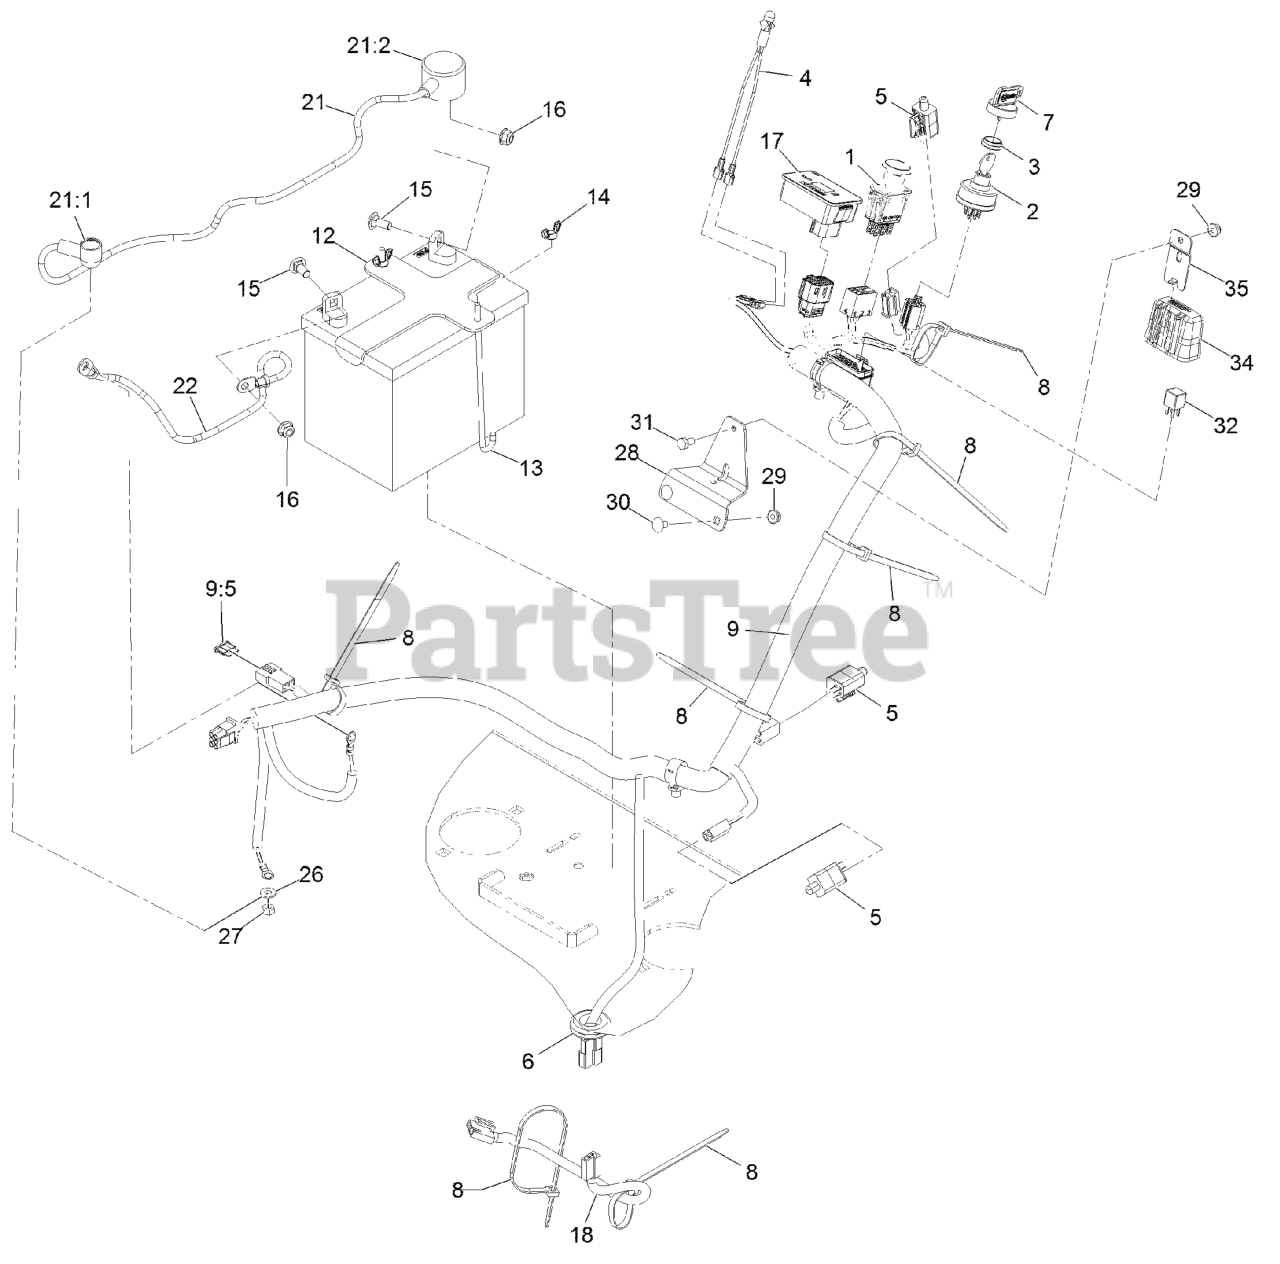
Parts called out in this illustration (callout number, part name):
1	SWITCH-PTO
2	SWITCH, KEY START
3	NUT-SWITCH, IGNITION
4	INDICATOR-LED, RED
6	GROMMET
7	KEY-IGNITION
8	TIE-PLASTIC
9	HARNESS-WIRE
9:5	FUSE-BLADE TYPE, 20 AMP
12	BRACKET, BATTERY HOLD DOW
13	BOLT-HOLDDOWN
14	WINGNUT
15	BOLT-CARR
16	NUT-HF, NI
17	MODULE-HOUR METER
18	HARNESS-CLUTCH PIGTAIL
21	POSITIVE BATTERY CABLE AS
21:1	INSULATOR-SOLENOID
21:2	INSULATOR-BATTERY
26	WASHER-FLAT
27	NUT-HEX
28	BRACKET-MOUNTING, FUSEBLO
30	SCREW-CARR
31	SCREW-HH
32	RELAY-MICRO
34	COVER-BLOCK, FUSE
35	CLIP-MOUNTING
